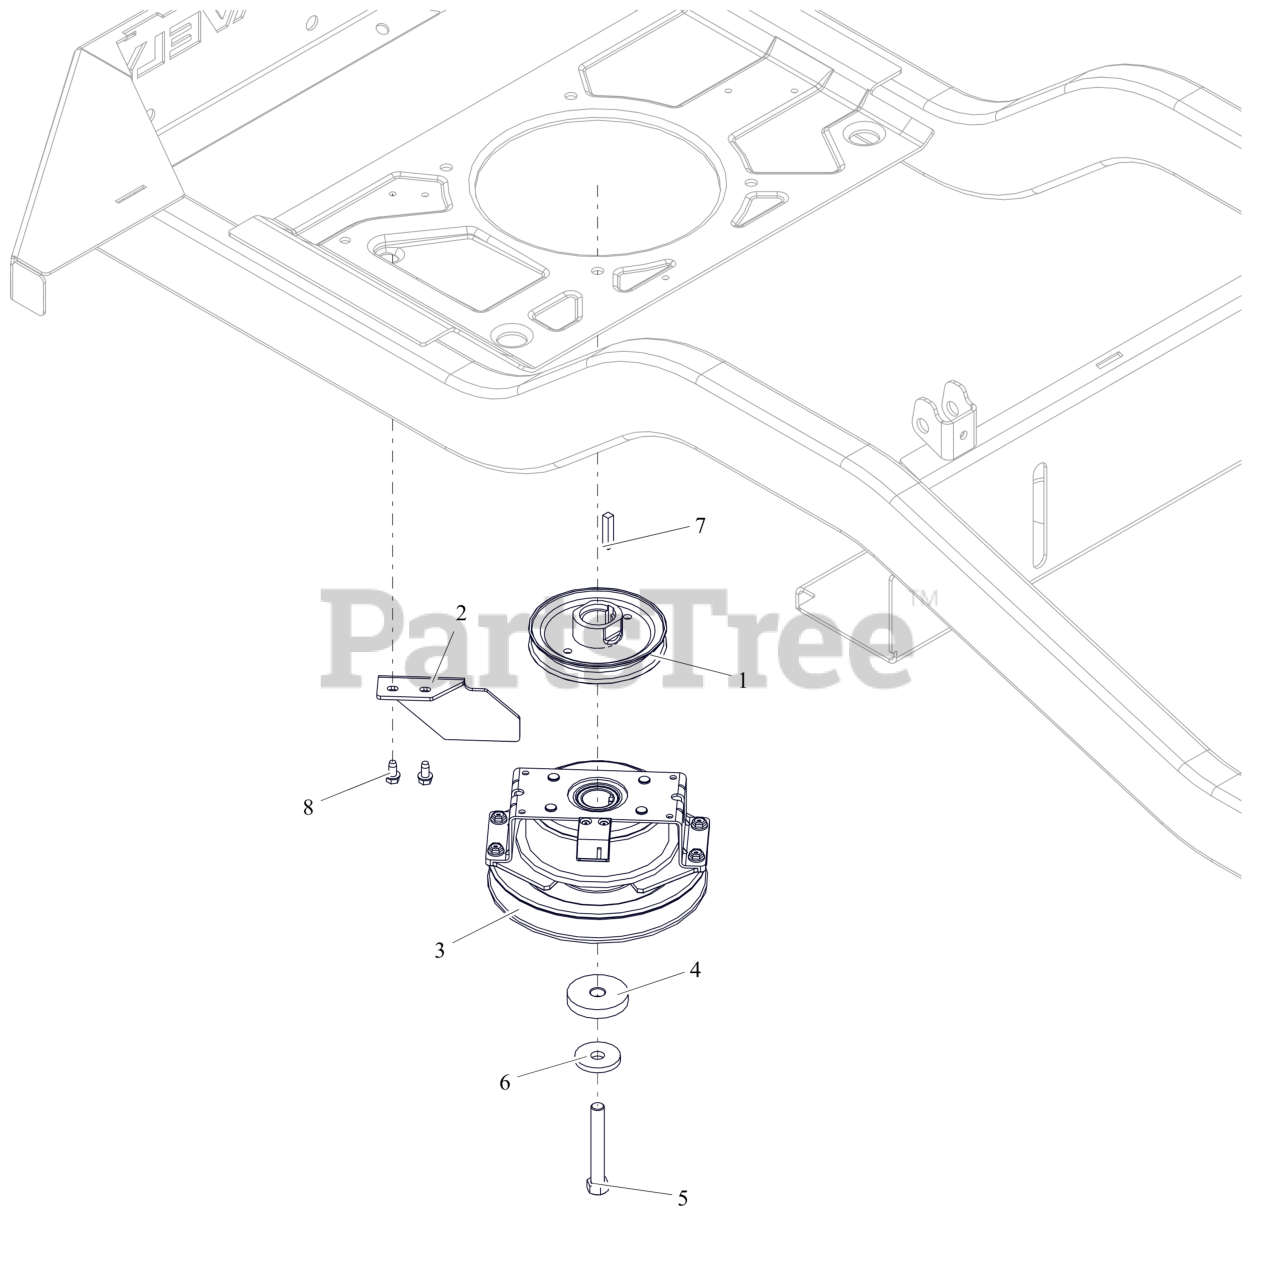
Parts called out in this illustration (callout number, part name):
1	WLDMT,PULLEY-4.50ODX1.003
2	BRKT, CLUTCH STOP HD
3	CLUTCH, OGURA DBL SPRG
4	SPACER, .474/.459X2.00X.350
5	BLT, HEX 0.4375-20X3 G8 ZCC NT
6	WASHER, 7/16" SPRING DISK
7	KEY-SQ .25 X 1.25 X .25 SAE
8	SCR-TAP .25-20X.50 HWH ZCC
